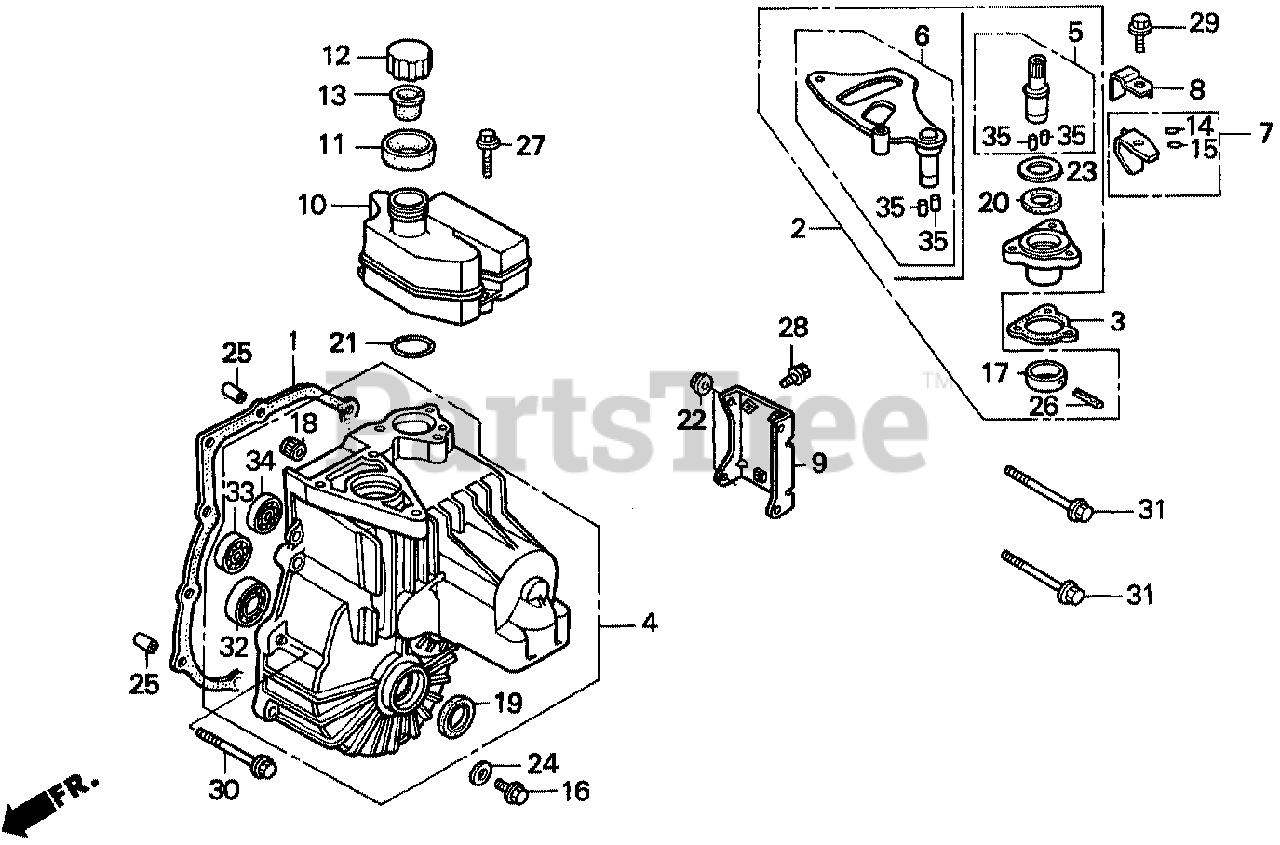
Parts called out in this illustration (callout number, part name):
1	GASKET, L. TRANSMISSION CASE
2	COVER, CONTROL SHAFT
3	GASKET, CONTROL SHAFT COVER
4	CASE, L. TRANSMISSION
5	SHAFT, CONTROL (NOT AVAILABLE)
6	SHAFT, CONTROL
7	STAY, SPOOL LEVER
8	HOLDER, SPOOL LEVER
9	BRACKET, TRANSMISSION (A)
11	RUBBER, SEAL
12	FRAME, OIL CAP
13	GASKET, OIL CAP
14	MARK, GREEN
15	MARK (RED)
16	BOLT, PLUG
17	COLLAR, CONTROL SHAFT
18	BEARING, NEEDLE (14MM) (TOYO)
19	OIL SEAL (20X38X10)
20	OIL SEAL (20X30X5)
21	O-RING (36X3.2)
22	NUT, FLANGE (8MM)
23	WASHER, PLAIN (20MM)
24	WASHER, DRAIN PLUG (14MM)
25	PIN, DOWEL (10X20)
26	PIN, SPRING (3X28)
26	PIN, SPRING (4X28)
27	BOLT, FLANGE (6X28)
28	BOLT, FLANGE (8X14)
29	BOLT, FLANGE (8X25)
30	BOLT, FLANGE (8X80)
31	BOLT, FLANGE (8X100)
32	BEARING, RADIAL BALL (6006)
33	BEARING, RADIAL BALL (6302)
34	BEARING, RADIAL BALL (6304)
35	ROLLER (6X18) (NOT AVAILABLE)
